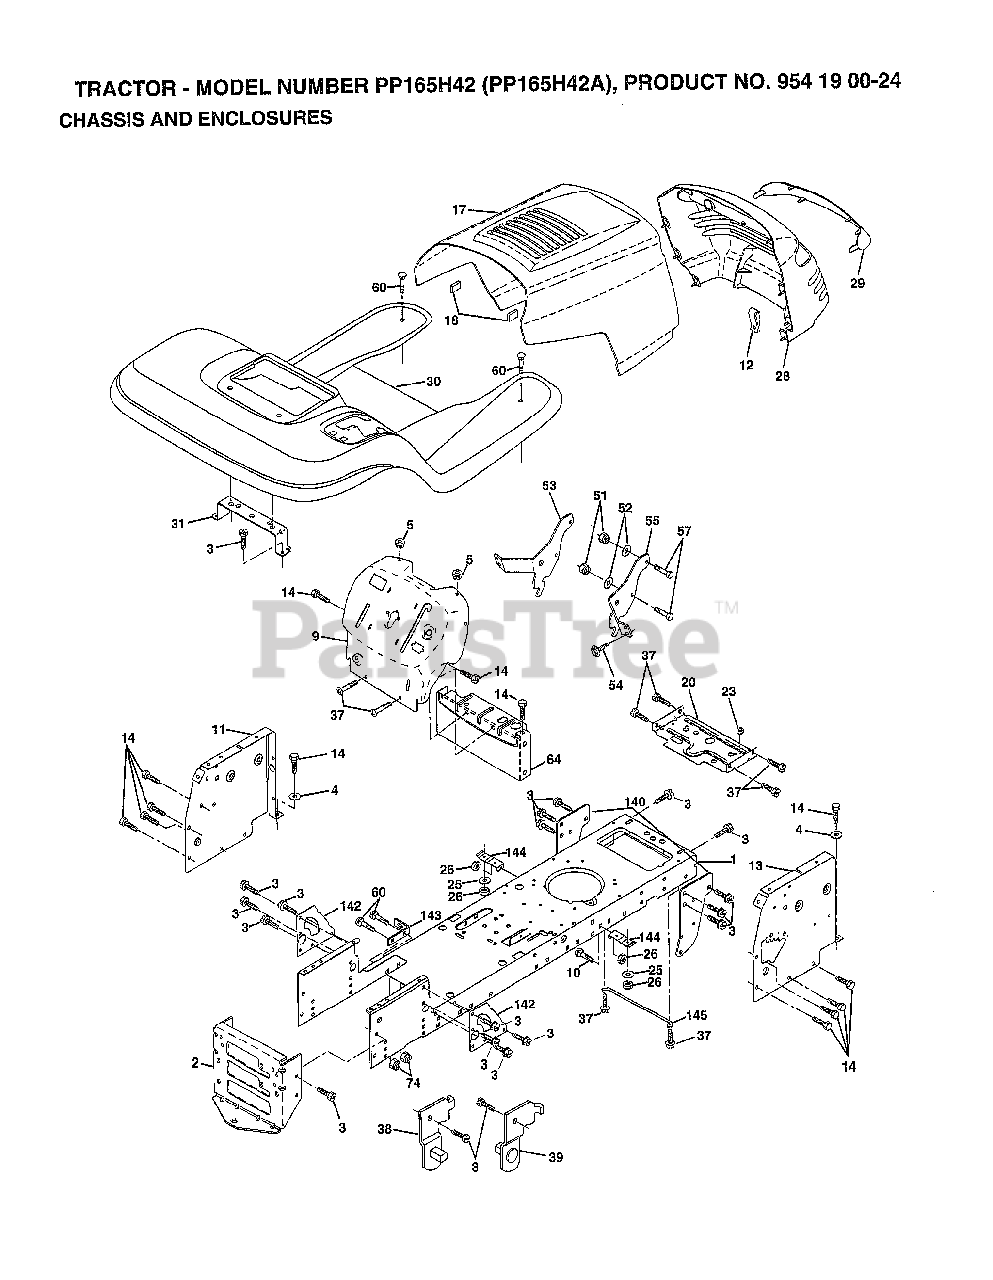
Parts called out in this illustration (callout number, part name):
1	CHASSIS
3	SCREW
4	WASHER
5	BUMPER-HOOD/DASH
11	"PANEL-DASH,LH"
12	CLIP.TINNERMAN
13	"PANEL-DASH,RH"
14	SCREW LT
17	"HOOD W/TRIM,MS428"
20	"PLATE-MTG,BATT/FU"
25	WASHER
26	NUT
28	GRILLE-MS428
29	LENS GRILLE
30	FENDER/FOOTREST
31	BRACKET SUPT FEND
38	BRACKET ASM LH
39	BRACKET ASM RH
51	NUT
52	WASHER
53	BRACKET.GRILLE.LH
54	SCREW.HEX.WS.HD
55	BRACKET.GRILLE.RH
60	BOLT
64	DASH-LOWER
140	BRKT SUSPENSION
142	PLATE.REINFORCEMT
143	"BRKT-S'BAR,CHASSI"
145	"ROD POVOT,CHASSIS"
